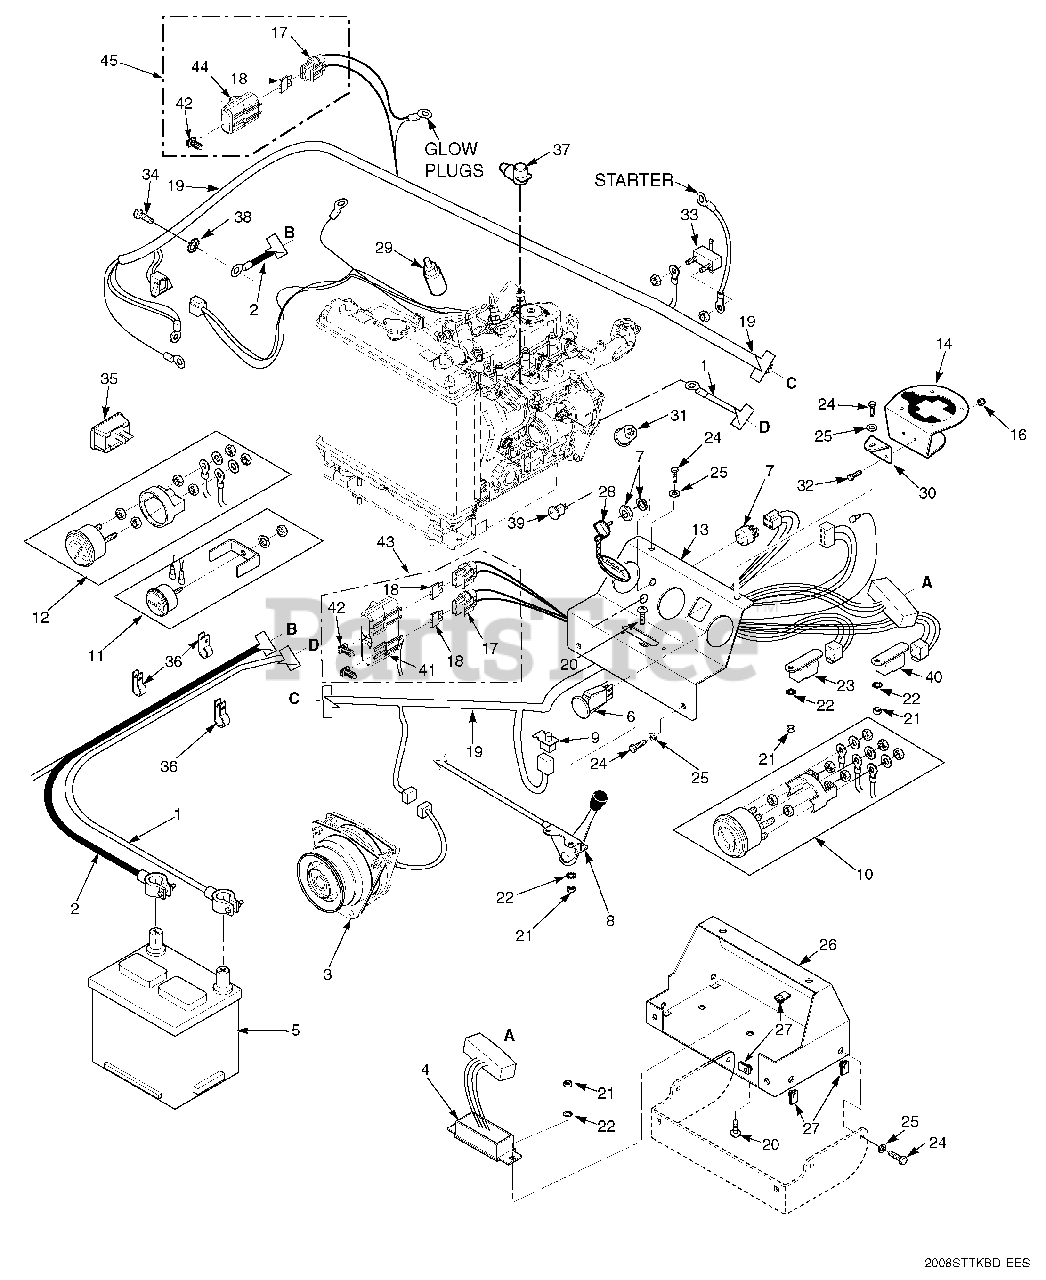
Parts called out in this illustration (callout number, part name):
1	Cable, Positive Battery
2	Cable, Negative Battery
3	Clutch, Electric PTO
4	Module, Interlock
5	Battery
6	Switch, PTO
7	Switch, Key
8	Cable, Control (Throttle)
9	Switch, Seat
10	Gauge, Water Temperature
11	Gauge, Oil Pressure
12	Gauge, Voltmeter
13	Panel, Instrument Panel
14	Cup Holder Accessory
15	Screw, #10-32 x 1.5" Phillips
16	Nut, #10-32 Elastic Stop
17	Fuse Holder
18	Fuse, 20 Amp
19	Harness, Wiring
20	Screw, #10-32 x .5" Phillips
21	Nut, Hex #10-32
22	Lockwasher #10
23	Relay
24	Bolt, Hex Hd. 1/4-20 x .75"
25	Lockwasher 1/4"
26	Base, Instrument Panel
27	U-Nut, 1/4-20
28	Key Assembly w/Fob
29	Sender Unit, Water Temperature
30	Cup Holder Mounting Bracket
31	Sender Unit, Oil Pressure
32	Bolt, Hex Hd. 1/4-20 x 3/4"
33	50 Amp Breaker
34	Bolt, Hex Hd. M8-1.25 x 14mm
35	Hour Meter
36	Clamp, Cable .5" ID
37	Boot, Positive Battery Terminal
38	Washer, Star
39	Indicator Light, Glow Plugs
40	Relay, 40 Amp
41	Cover, Sealed Double
42	Clip, Wire
43	Double Fuse Assembly, Sealed
44	Cover, Sealed Single
45	Single Fuse Assembly, Sealed
